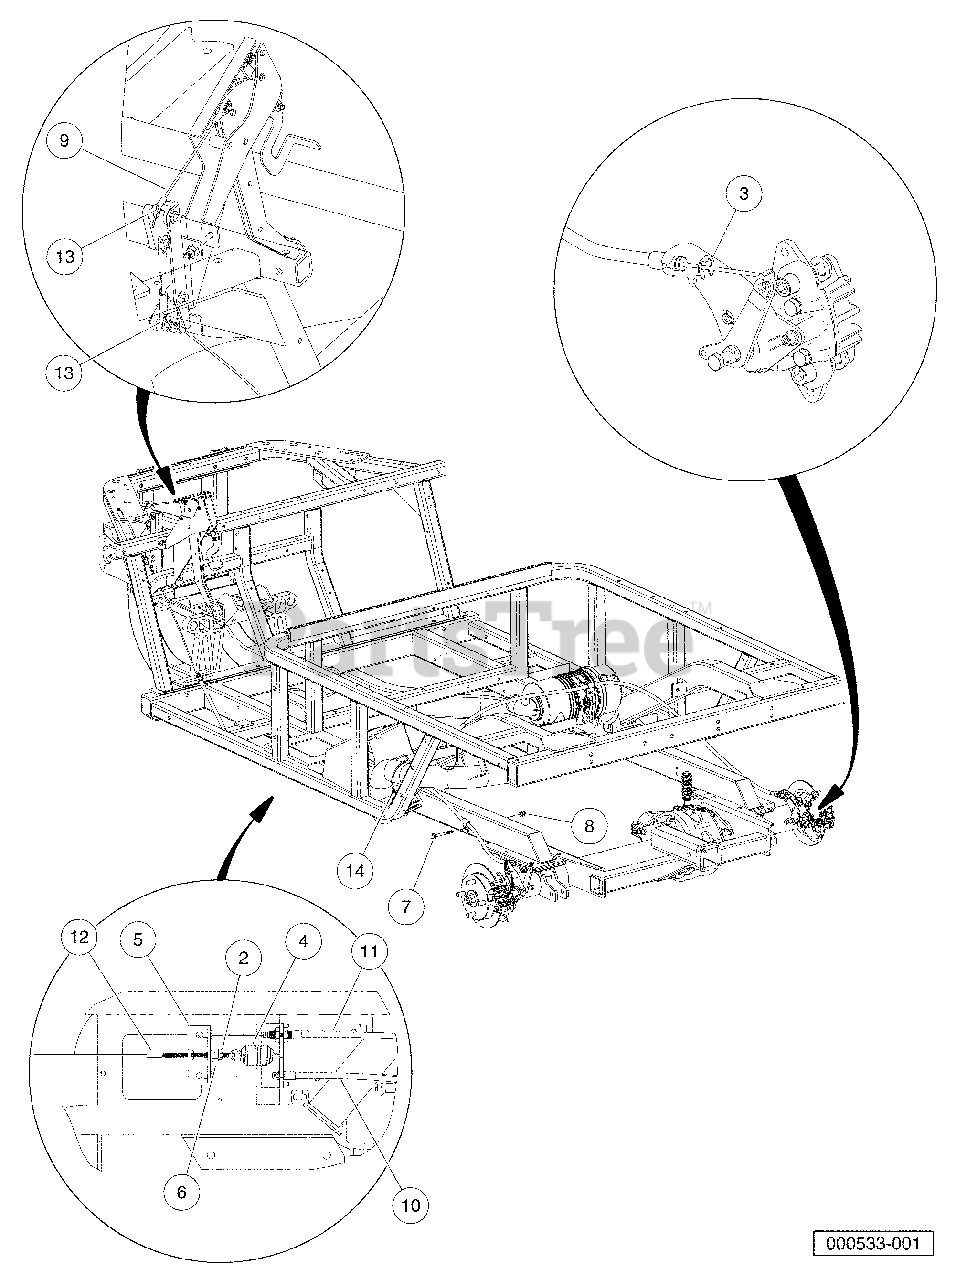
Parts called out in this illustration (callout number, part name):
1	Instl, Brake, Park, AWD
2	Nut, 5/16-24 Hex
3	E-Clip, 1/2
4	Spring, Brake Return
5	Equalizer Bracket
6	Nut, 5/16-24 Hex Cone
7	Bolt Flanged Head, M8 X 1.25 X 65
8	Lock Nut, Flg M8 X 1.25 Nylon.
9	Cable, Crank, Bell, Front
10	Cable, Noncoated, Pbrake, Left
11	Cable, Noncoated, Pbrake, Rght
12	Cable, Crank, Bell, Main
13	Cotter Pin, 3/32 x 1
14	Tie Wrap, 11" Nylon
